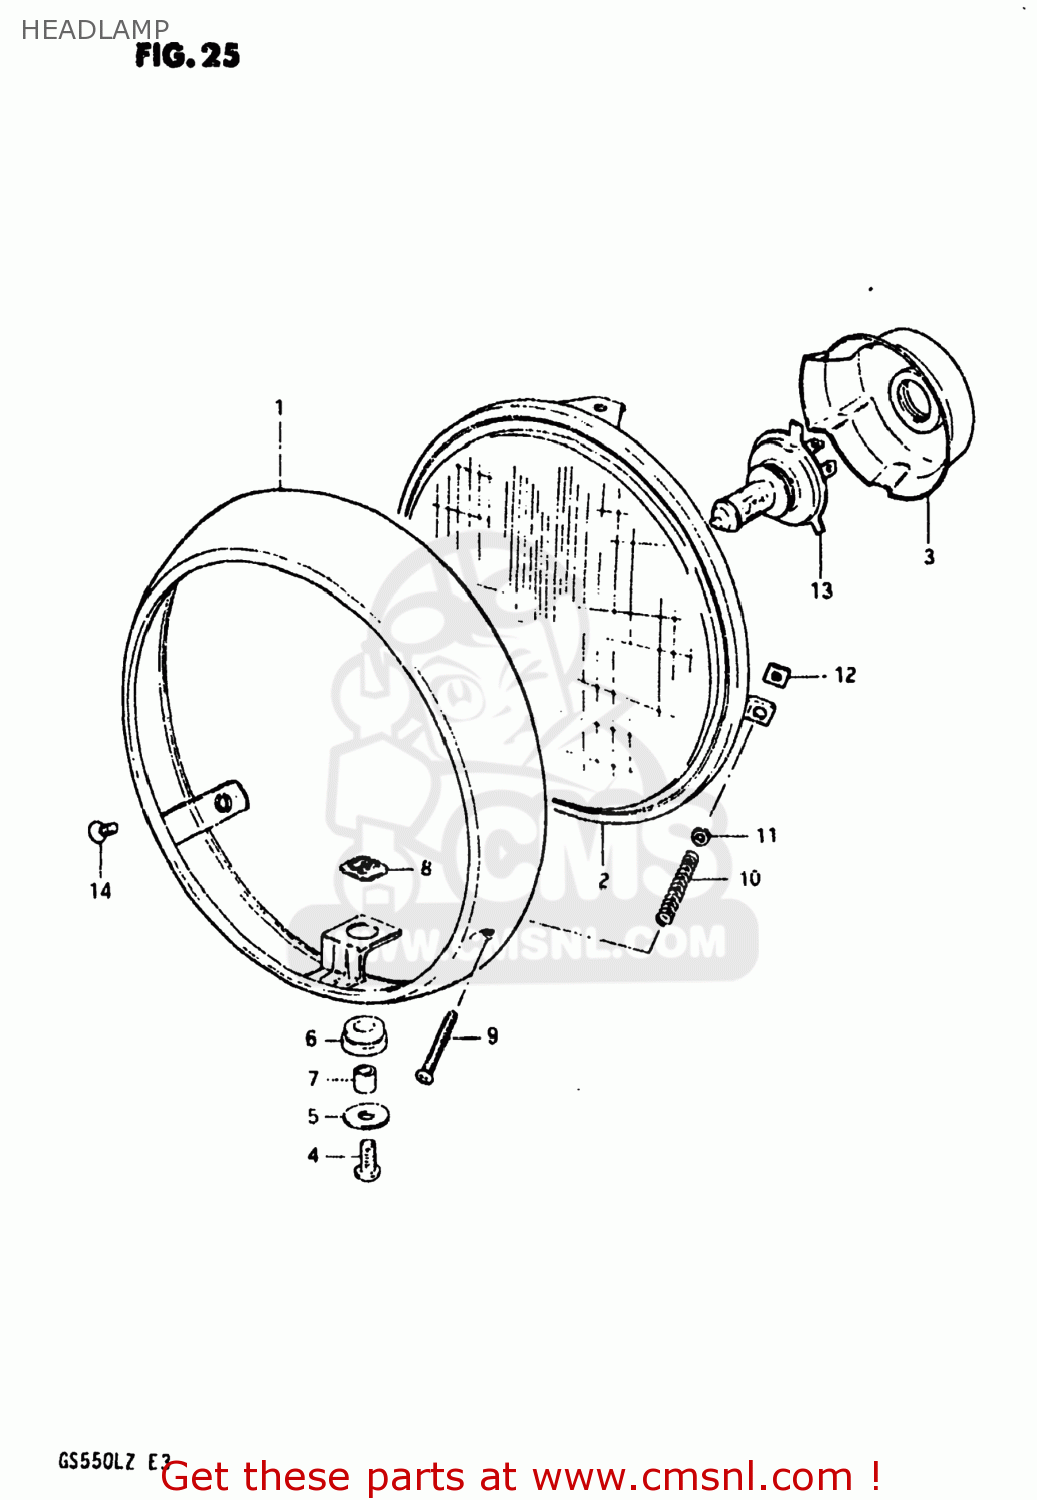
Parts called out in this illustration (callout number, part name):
1	RIM
2	LAMP UNIT
3	COVER,SOCKET
4	SCREW
5	WASHER
6	CUSHION
7	SPACER
8	NUT
9	SCREW
10	SPRING,HEADLAMP ADJUST
11	WASHER
12	NUT,HEADLAMP ADJUSTER
13	BULB(12V60/55W,H4)
14	SCREW(5X12)
